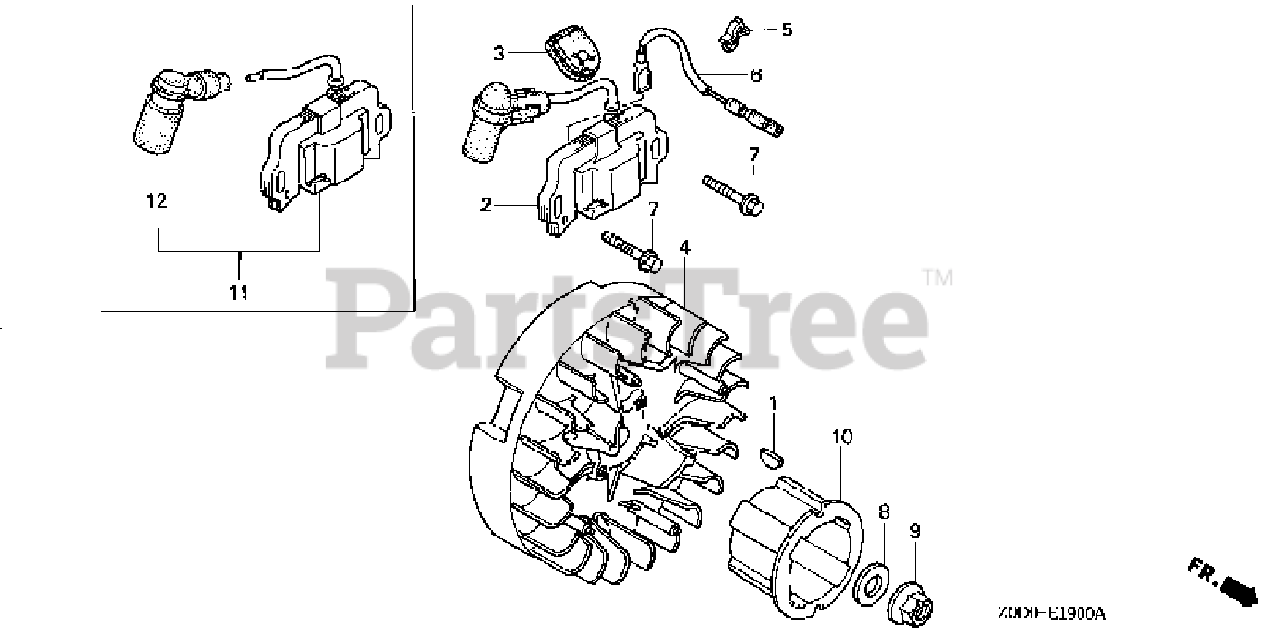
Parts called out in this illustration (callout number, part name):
1	KEY, SPECIAL
2	COIL ASSY., IGNITION
3	GROMMET, WIRE
4	FLYWHEEL
5	CLIP, IGNITION WIRE (8MM)
6	WIRE, STOP SWITCH
7	BOLT, FLANGE (6X20) (CT200)
8	WASHER (12MM)
9	NUT, FLANGE (12MM)
